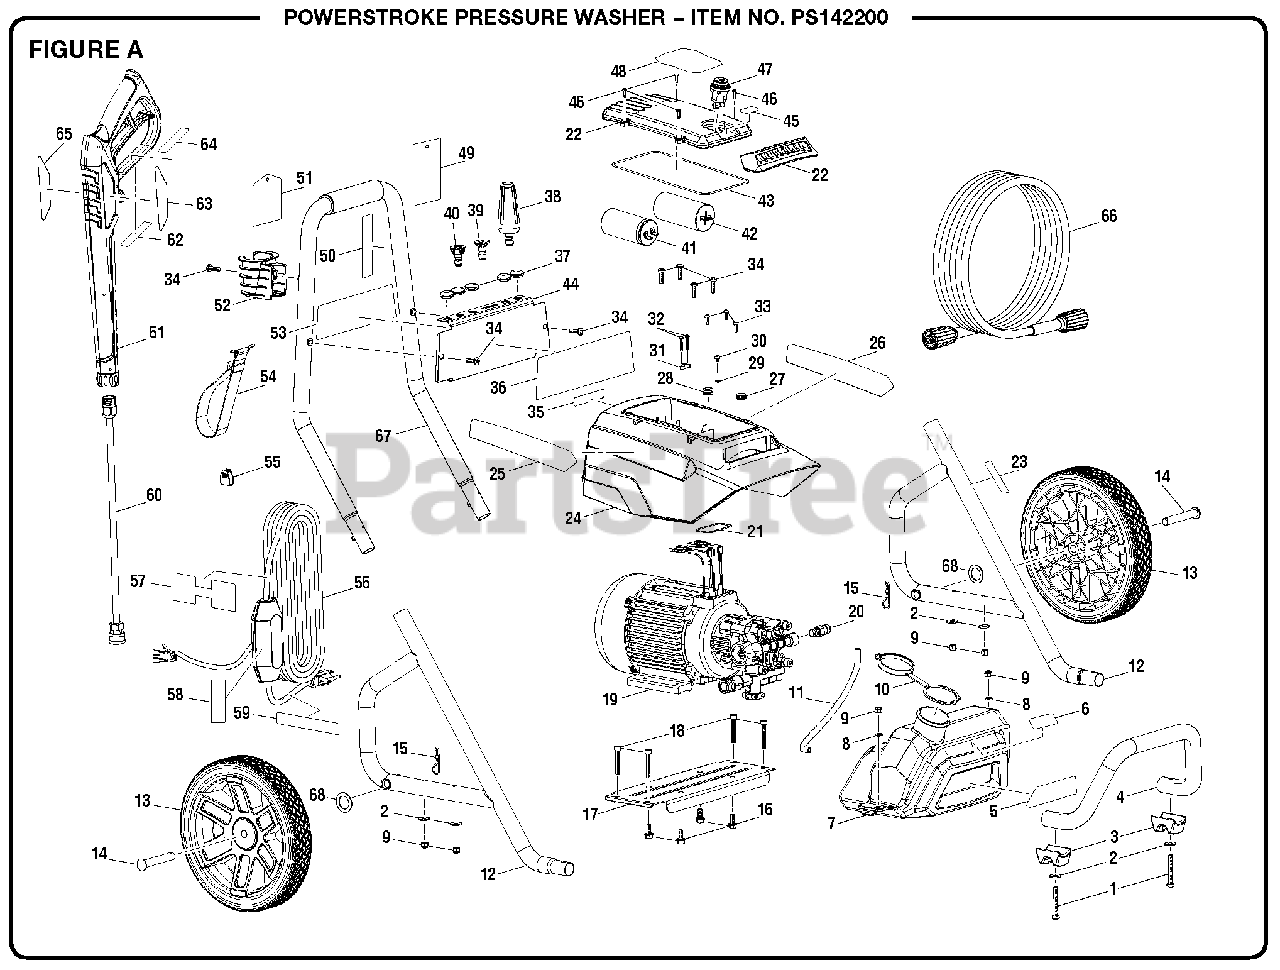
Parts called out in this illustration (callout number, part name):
1	Screw (M6 x 48 mm, T30 Torx Pan Hd.)
2	Washer (M6)
3	Rubber Foot
4	Frame Assembly (Front)
5	Detergent Tank Logo Label
6	Detergent Tank Label
7	Detergent Tank
8	Washer (M6)
10	Detergent Tank Cap
11	Injection Hose
12	Frame Assembly
15	Cotter Pin
16	Bolt (M6 x 16 mm, Flange Hex Hd.)
17	Motor Plate
18	Bolt (M6 x 40 mm, Socket Hex Hd.)
19	Motor and Pump Assembly
20	Thermal Release Valve
22	Upper Housing Assembly
23	Inquiries Label
24	Motor Shroud
25	Beauty Wing Label (Right)
26	Beauty Wing Label (Left)
27	Water Seal
28	Rubber Grommet
29	Lock Washer (M4)
30	Bolt (M4 x 6 mm, Pan Hd.)
31	Cord Clamp
32	Screw (M3.5 x 20 mm)
33	Bolt (M4 x 12 mm, Pan Hd.)
34	Bolt (M6 x 20 mm, Pan Hd.)
35	Regulatory Danger Label
36	Performance Label
37	Rubber Grommet
38	Turbo Nozzle
39	Soap Nozzle
40	15deg Nozzle
41	Capacitor
42	Capacitor
44	Face Panel
45	On/Off Label
46	Screw (M4.2 x 15 mm, Pan Hd.)
47	On/Off Switch
48	Brushless Label
49	Danger Hangtag (Spanish)
50	Quick Start Label
51	Nozzle Hangtag
52	Wand Holder
53	Danger Label
54	Hose Holder Strap
55	Cord Clip
56	Power Cord
57	Cord Wrap Label
58	GFCI Plug Label
59	Outlet Cord Wrap Label
60	Spray Wand Assembly
61	Trigger Handle
62	Rating Label
63	Trigger Handle Warning Label (English)
64	Trigger Handle Warning Label (French/Spanish)
65	Trigger Handle Logo Label
66	High Pressure Hose
67	Handle Assembly
68	Washer (OD21 x 14 x 1t)
